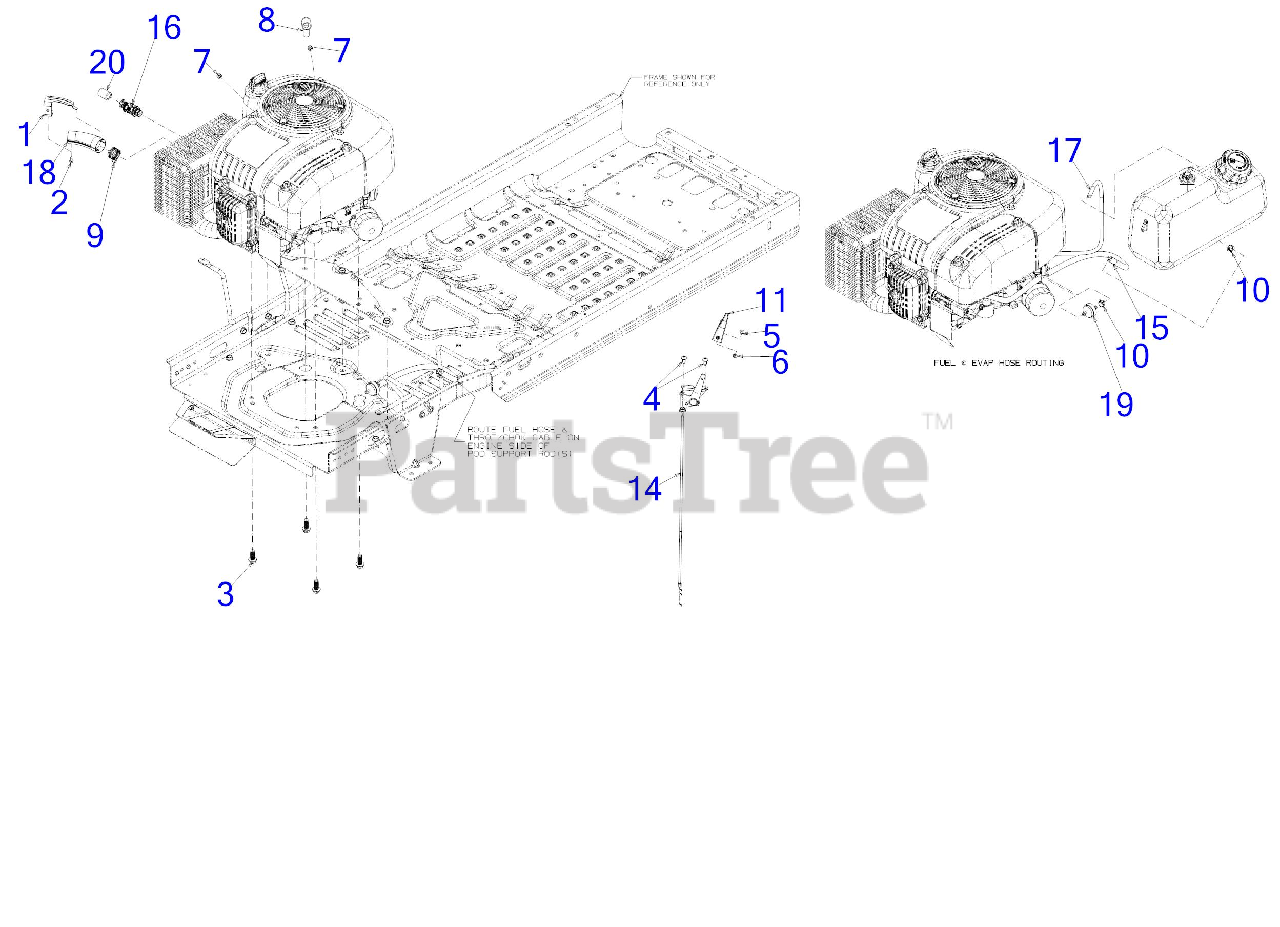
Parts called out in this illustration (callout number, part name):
1	EXHAUST DEFLECTOR GUARD
2	HEX SCREW WASHER HD #8-18 x 0.500
3	SCREW 3/8-16 x 1
4	SCREW 1/4-20 x .5
5	SCREW #8-32X.38 LG
6	HEX NUT 8-32
7	HEX NUT
8	TERMINAL COVER BLACK
9	HOSE CLAMP-5/8
10	HOSE CLAMP 1/20
11	THROTTLE CONTROL KNOB
14	THROTTLE/CHOKE CABLE 19.0
15	FUEL HOSE LOW PERMEATION
16	OIL DRAIN VALVE
17	VENT HOSE 3/16 ID
18	EXHAUST DEFLECTOR
19	FUEL FILTER
20	DRAIN HOSE 14''
